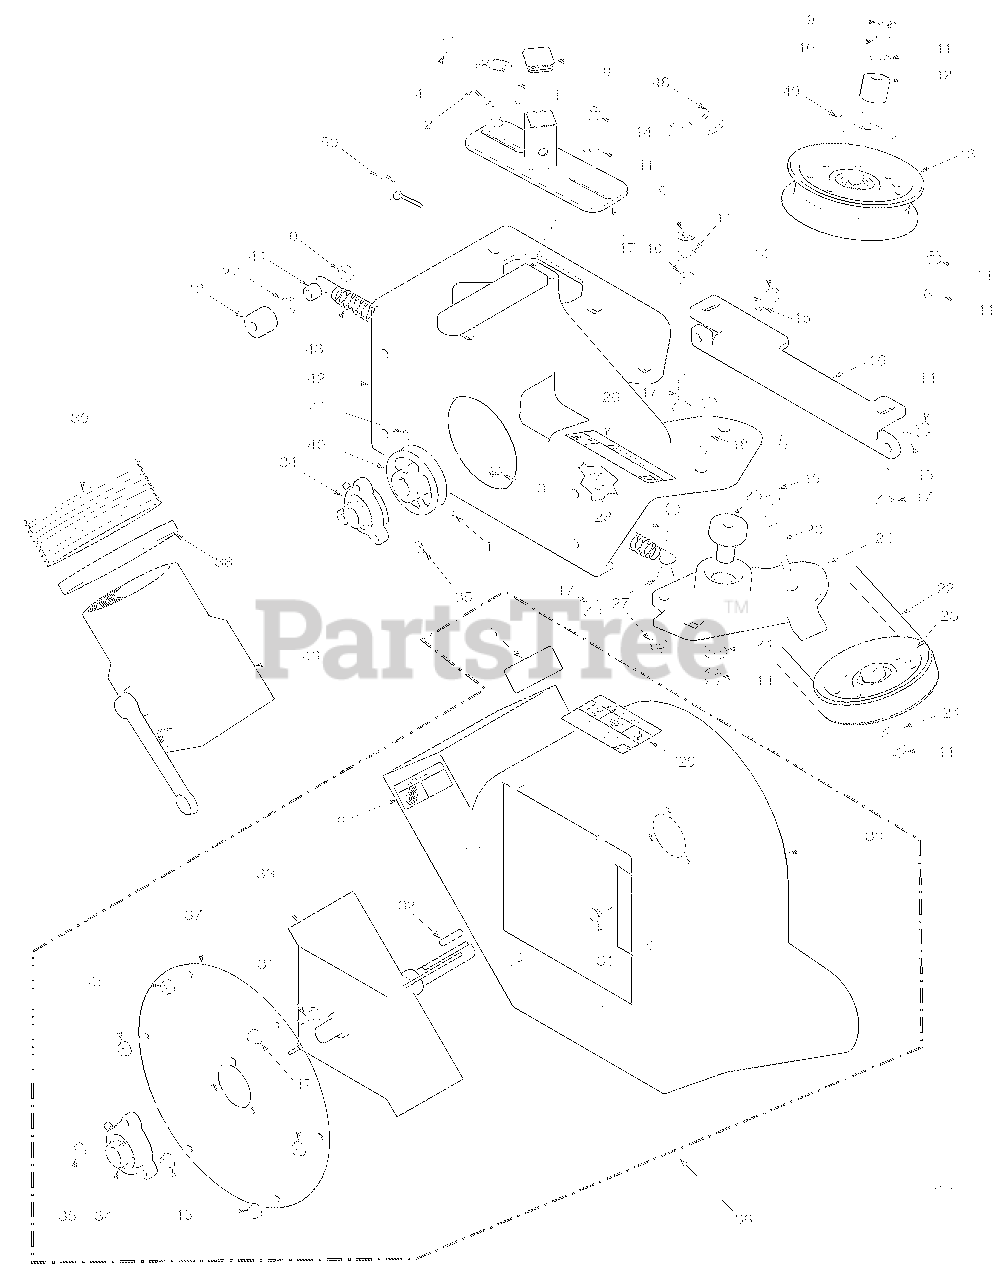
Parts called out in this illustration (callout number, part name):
1	Pin, Ring 2-1/4" Long
2	Lanyard, Deck Height Pin
3	Nut, Serr. Flange 1/4-20
4	Bolt, Hex Head 1/4-20 x 1-1/4"
5	Decal, Blower
6	Decal, Rotating Blower
7	Grip, Blower Lever
8	Cap, Square
9	Nut, Push On 3/8 Thread
10	Lock Nut, 3/8-16
11	Flatwasher, 3/8-.391 x .938 x .105
12	Spacer
13	Pulley, Idler 4" Dia.
14	Nut, Elastic Stop 3/8-16
15	Lockwasher, 3/8-16
16	Plate, Catcher Mounting
17	Bolt, Carr. 3/8-16 x 1-1/2"
18	Bolt, Hex Head 3/8-16 x 3" - 52"
19	Bolt, Hex Head 3/8-16 x 3-1/2"
20	Bolt, Hex Head 3/8-16 x 1-3/4"
21	Idler Arm Assembly
22	Belt, GC-STC
23	Pulley, 3-1/2" O.D., GC-STC
24	Washer, 3/8 Hardened
25	Pivot, Idler
26	Decal, Belt Cover
27	Nut, Serr. Flange 3/8-16
28	Bolt, Hex Head 3/8-16 x 1-1/2 Gr. 8
29	Decal, Danger
30	Blower Housing Weldment
31	Bolt, Carr. 5/16-18 x 3/4" Gr. 5
32	Key, 1/4 x 1/4 x 1-1/2"
33	Fan Weldment
34	Bearing Assembly
35	Nut, Elastic Stop 5/16-18
36	Blower Housing Assembly, GC-STT
37	Cover, Blower Housing
38	Clamp, 8-5/8" Max Dia.
39	Hose, 8.00" Dia. x 53" Long
40	Pulley, 4-3/4" O.D. - 1" Bore
41	Set Screw, 5/16-18 x 3/8"
42	Frame, Blower Mount
43	Spring, Main Drive
44	Spacer
45	Nut, Serr. Flange 5/16-18
46	Adapter w/Strap
47	Receiver Weldment, Mounting Post
48	Hair Pin Cotter, .177 x 3-1/4"
49	Dust Shield
50	Quick Pin, 5/16" Dia.
